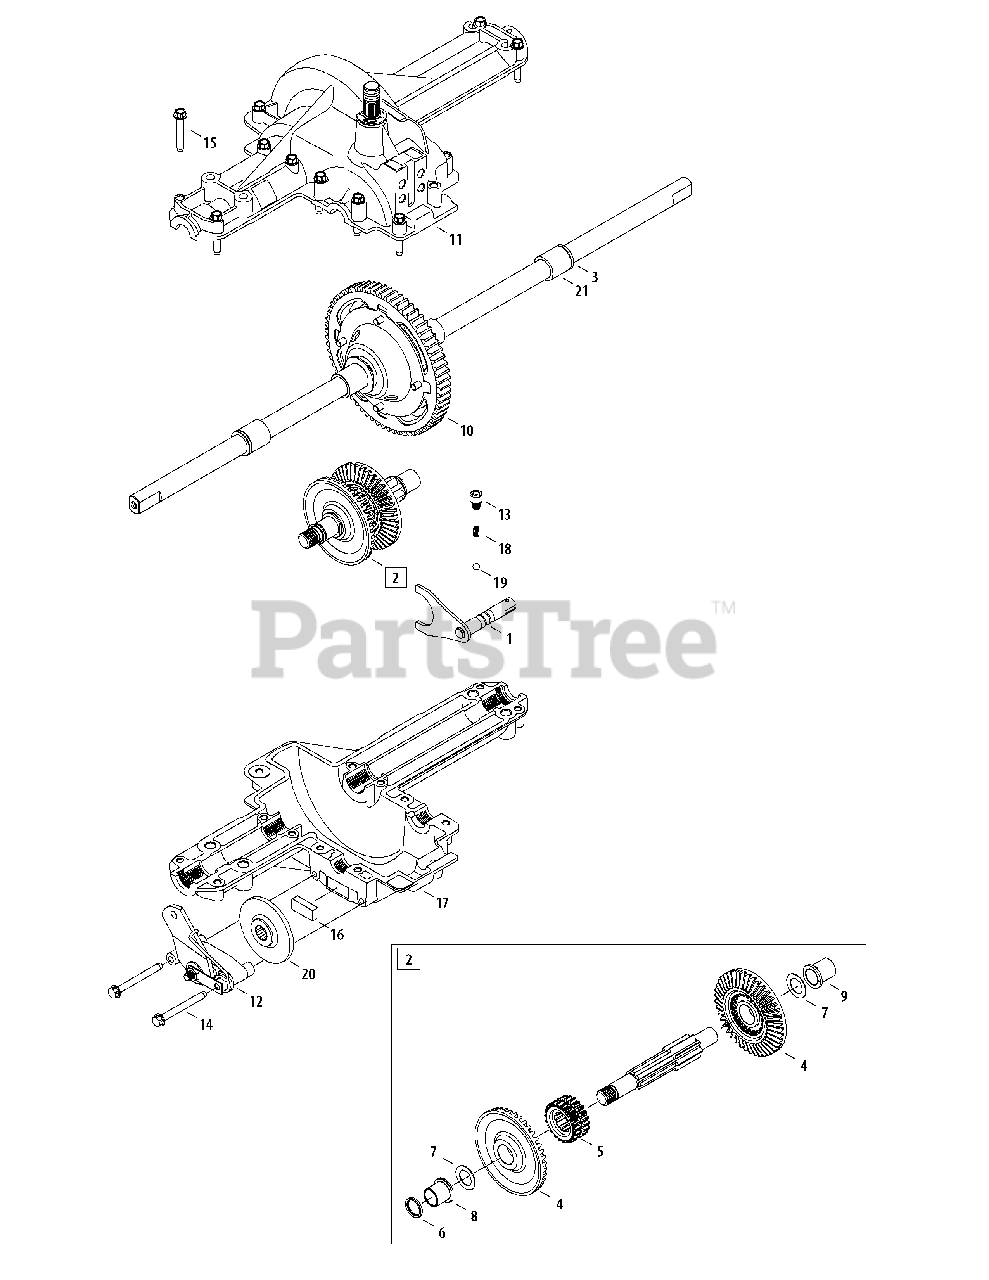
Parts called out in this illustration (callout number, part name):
1	Detent Shaft Assembly
2	Drive Shaft Ass’y (Incl. Ref. 3-9)
4	Bevel Gear 42T
5	Single Speed Clutch Collar
6	Seal .625 x .812 x .94
7	Shim Washer .625 ID x 1.0 OD x .030
7	Shim Washer .634 ID x 1.0 OD x 0.04
7	Shim Washer .630 ID x 1.0 x .020
7	Shim Washer .632" ID x 1.0 OD x .035
7	Shim Washer .632" ID x 1.0" OD x .025
8	Flange Bearing 5/8 x 3/4 x 3/4
9	Flange Bearing 5/8 x 3/4 x 15/16
10	Differential Assembly
11	Upper Housing
12	Brake Ass’y
13	S-Tapping Screw 5/16-18 x .375
14	Hex Wash. Hd. Self-Tap Scr. 1/4-20
15	S-Tapping Screw 1/4-10 x 1.625
16	Brake Puch
17	Lower Housing
18	Compression Spring
19	Ball Detent .250 Dia.
20	Brake Disc
21	Sleeve Bearing 3/4 ID x 1.0
